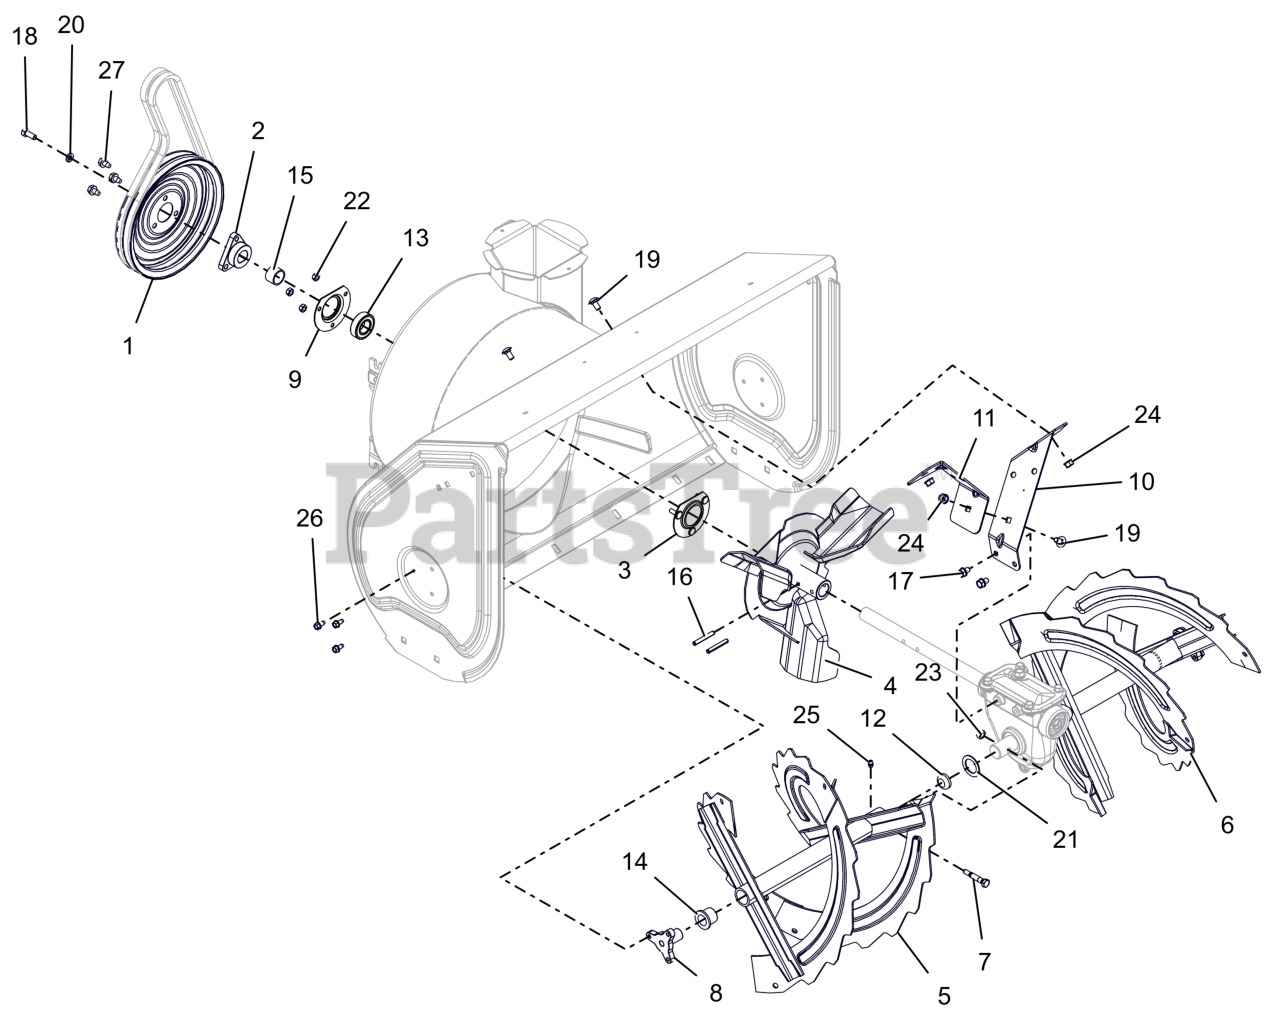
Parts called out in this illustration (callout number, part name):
1	PULLEY, SPIN FORM DUAL GROOVE
2	PULLEY HUB, D-BORE .87 PRO
3	BEARING FLANGE
4	IMPELLER, 3 BLADE-14"
5	RAKE, RH W/ZERK - 30"
6	RAKE, LH W/ZERK - 30"
7	SHEAR BOLT SERVICE ASSEMBLY
8	SUPPORT, RAKE BUSHING
9	BEARING FLANGE
10	BRACKET, GEARCASE SUPPORT - LH
11	BRACKET, GEARCASE SUPPORT - RH
12	PLUG, RAKE TUBE
13	BRG-BALL .876 X 1.750 X .50
14	BSHG-FLG, NY.778 ID X 1.018 OD
15	BSHG,SPCR .895X1.065X.693
16	PIN-ROLL .250X1.75
17	BLT, SEMS .31-18X.50 G5 ZCC
18	BLT, HEX .31-24X.750 G5 ZCC
19	BLT,RHSSN.31-18X.625 G5 ZCCP30
20	WSHR, LK-HVY .312X.097 ZCC
21	WSHR, FLT 1.010X1.505X.062 ZCC
22	NUT,LK-CTR .25-20 GA ZCC
23	NUT,LK-CTR .31-18 GA ZCC
24	NUT-LK-TOP-FLG .312-18 GF ZCC
25	ZERK,FITTING .25X.125 DRIVE IN
26	SCR-TAP .25-20X.50 HWH ZCC
27	SCR,TAP .312-18X.50 HWH TR ZCC
